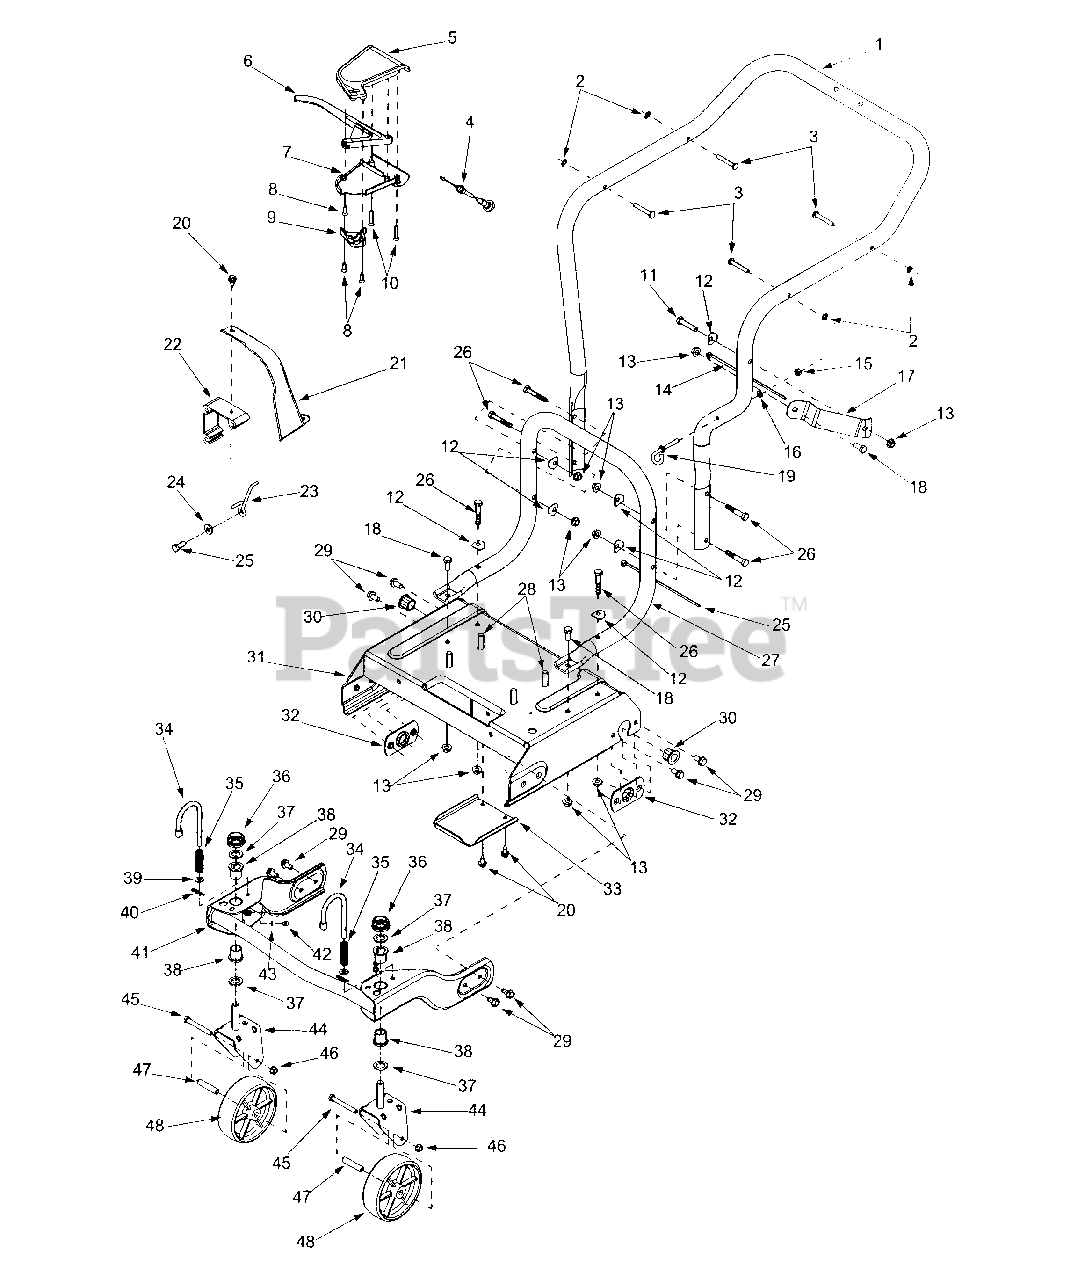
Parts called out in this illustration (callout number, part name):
2	Push Nut
3	Stud Pin .250 x 1.75
4	Clutch Cable 56"
5	Upper Clutch Cover
6	Drive Lever
7	Lower Clutch Cover
8	Screw #10-12 x .750
9	Mounting Cable Cap
10	Screw #10-16 x 1.25
11	Hex Cap Screw 5/16-18 x 1.50
12	Shoulder Washer.320 ID x .93 OD
13	Hex Flange Lock Nut 5/16-18
14	Cable Tie
15	Hex Nut 1/4-28
16	Lock Washer 1/4
18	Hex Cap Screw 5/16-18 x .75
19	Eye Bolt
20	Hex Washer Screw 1/4-14 x .625
21	Belt Cover
22	Engine Mounting Adapter
23	Belt Keeper
24	Flat Washer .344 x .75 x .12
25	Hex Cap Screw 5/16-24 x .75
26	Hex Cap Screw 5/16-18 x 1.75
28	Screw 3/8-16 x 1.25
29	Hex Washer Screw 5/16-18 x .625
30	Hex Flange Bearing .631 x .720
32	Axle Bracket
33	Transmission Cover
34	Lock Pin
35	Compression Spring
36	Push Cap
37	Flat Washer 5/8 ID x 1.0 OD
38	Flange Bearing .632 ID
39	Flat Washer .330 ID x .630 OD
40	Cotter Pin
42	Grease Fitting 3/16
43	Flat Washer .203 ID x .403 OD
45	Hex Cap Screw 3/8-16 x 3.0
46	Flange Lock Nut 3/8-16
47	Spacer
48	Wheel 6.0 x 2.0
